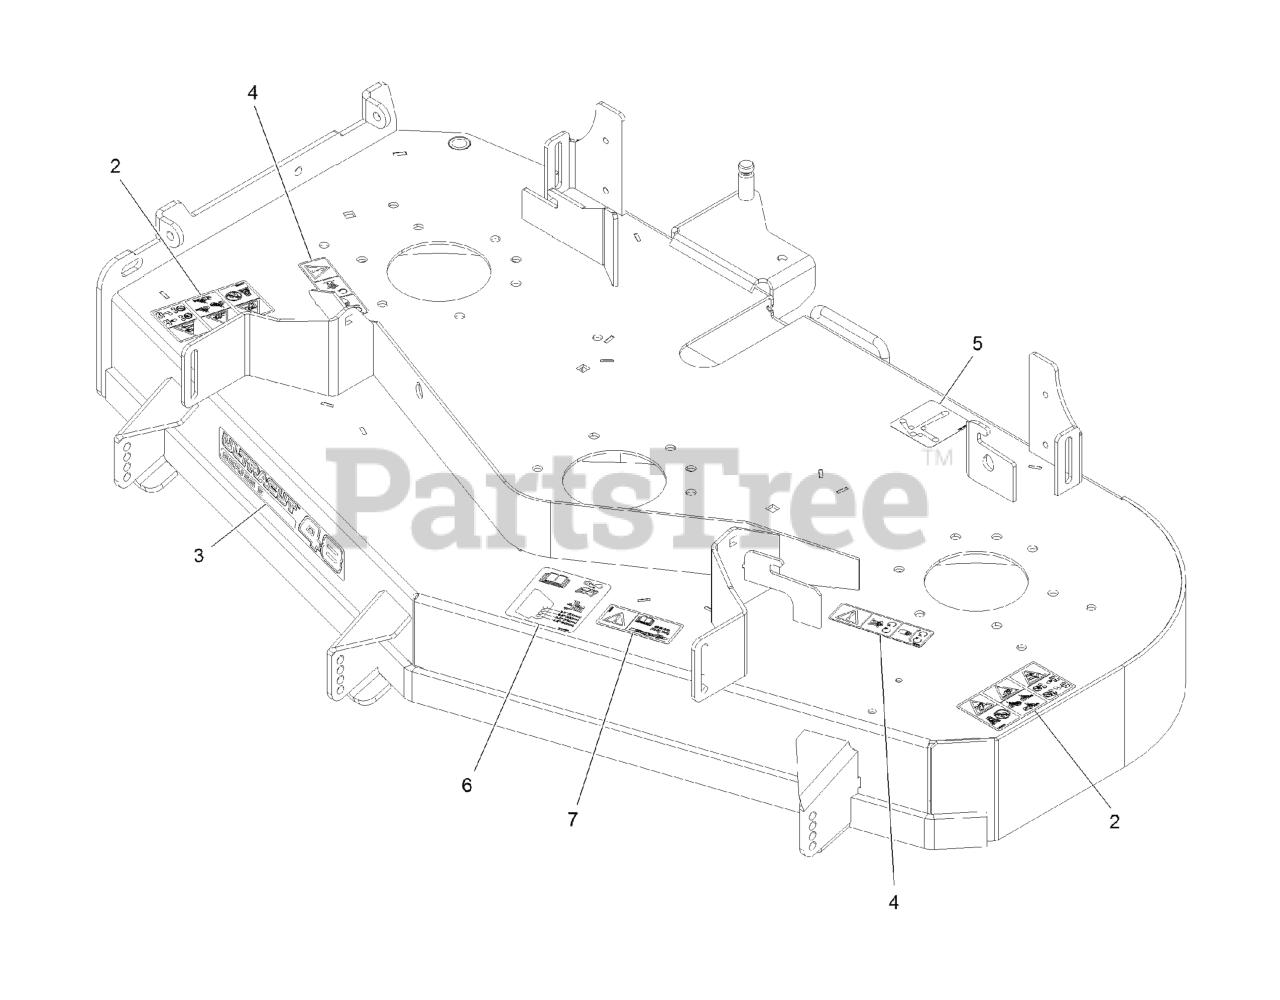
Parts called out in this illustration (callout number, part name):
2	DECAL-DANGER THROWN OBJECTS
3	DECAL-ULTRACUT 48 SERIES
4	DECAL-COVER, MISSING
5	DECAL-ROUTING, BELT
6	DECAL-ROLLER, ANTI-SCALP
7	DECAL-BOLT TORQUE
